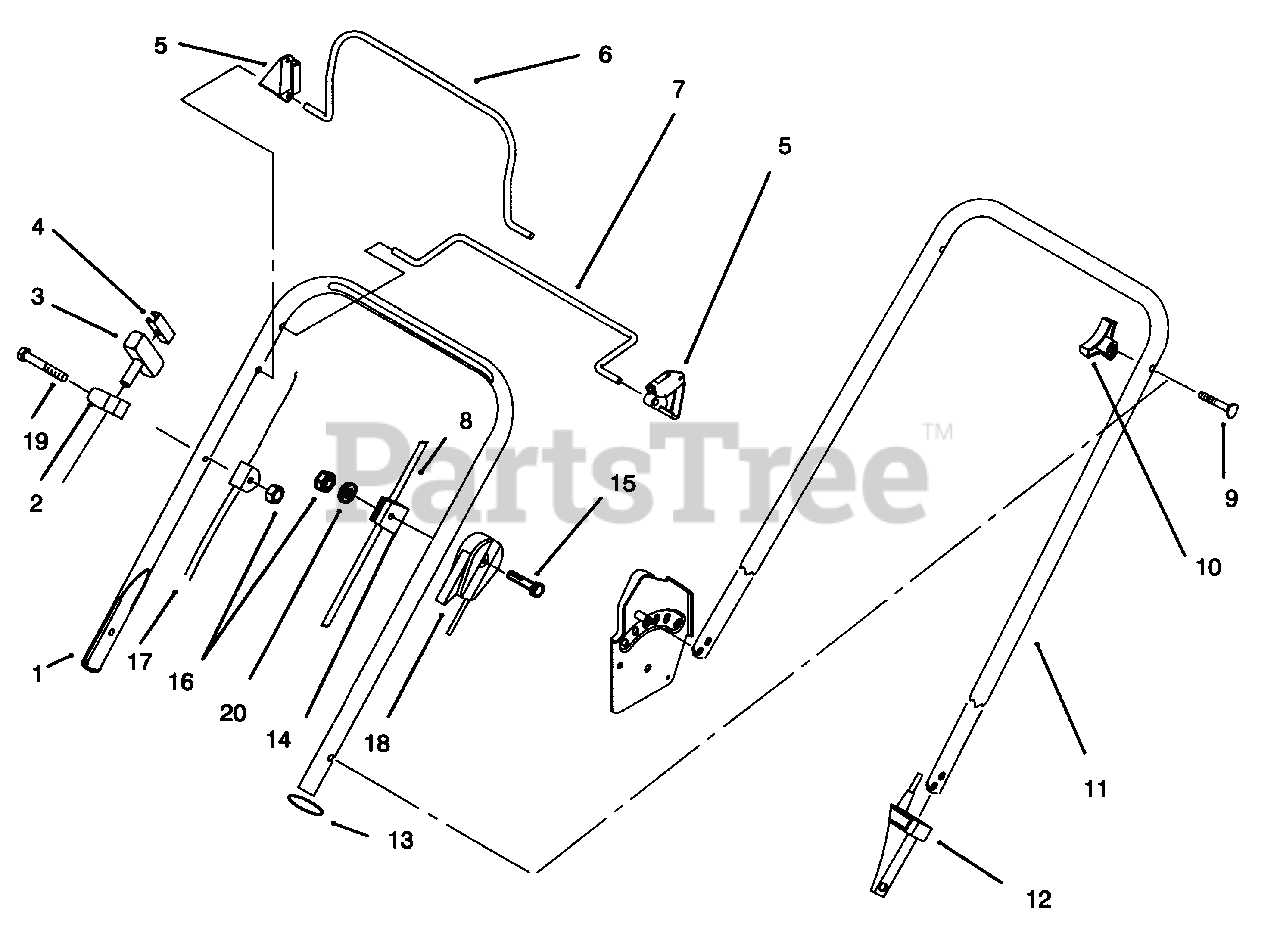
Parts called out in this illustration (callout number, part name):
1	Handle-Upper
2	Guide-Rope
3	Handle-Starter
4	Clip-Rope Insert
5	Stop-Pivot
6	Bail-Brake
7	Bail-Control (Self Propelled)
8	Cable-Traction
9	Screw-Handle
10	Knob-Handle
11	Handle-Lower
12	Anchor-Cable, (Lower) Self Propelled
13	Tie Strap
14	Anchor-Cable (Upper) Self Propelled
15	Screw (Hand Push)
17	Cable-Brake
18	Cable-Throttle
20	Washer (HandPush)
